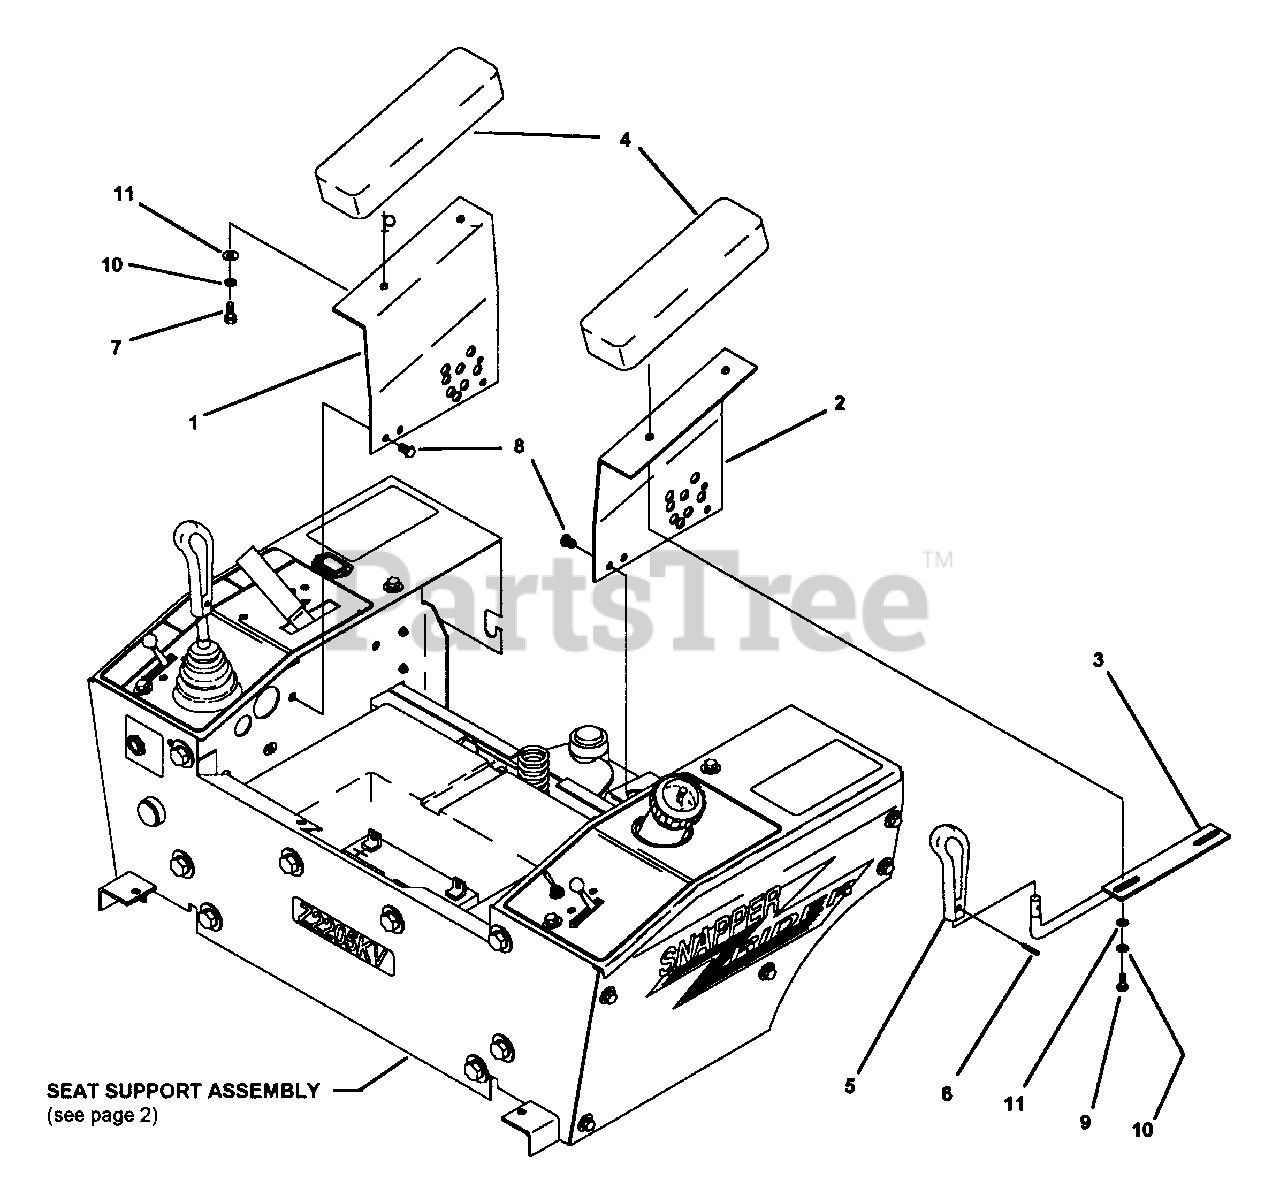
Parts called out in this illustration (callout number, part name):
1	ARM REST SUPPORT R.H.
2	ARM REST SUPPORT L.H.
3	SECURITY HANDLE WELDMENT
5	HANDLE, JOYSTICK, 7/16" BORE
6	PIN, SPIRAL ROLL, 3/16 X 1" LIGHT DUTY
7	BOLT, 5/16-18 X 3/4" GR.5
9	BOLT, 5/16-18 X 1" GR.5
10	LOCKWASHER, 5/16" HEAVY SPRING
11	WASHER, FLAT STD. 5/16"
